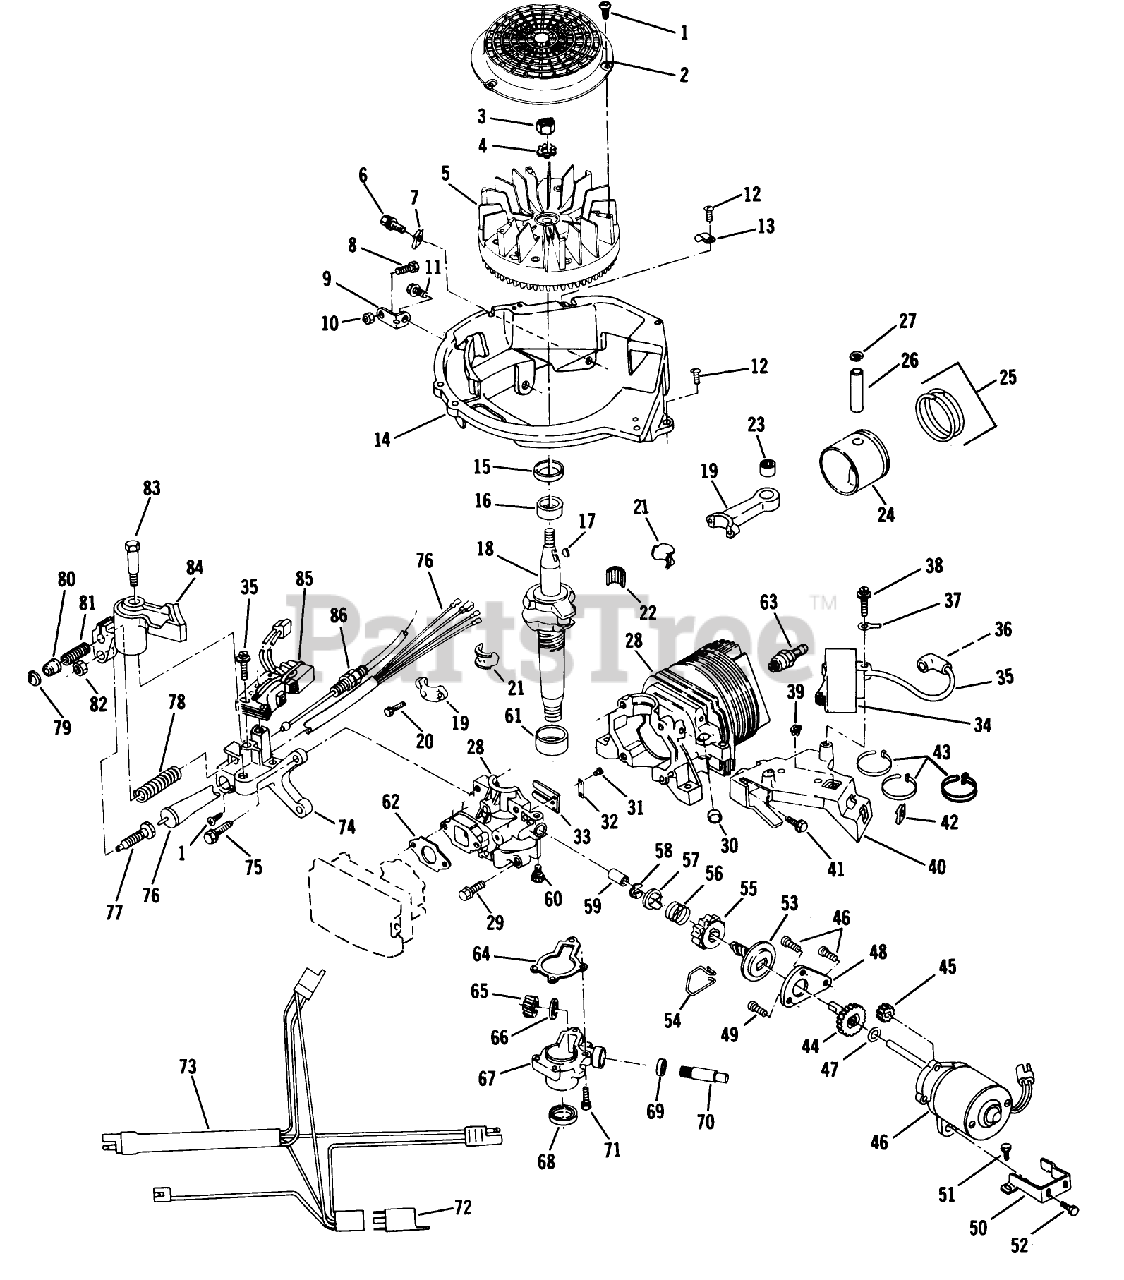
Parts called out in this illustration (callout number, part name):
1	SCREW F
2	SCREEN F'WHEEL S
3	NUT
6	SCREW-SEMS
8	BOLT F
10	NUT-LOCK F
12	SCREW F
14	BASE SHROUD F
16	BEARING V
17	KEY
20	SCREW-HSH
21	LINER ASM
23	BEARING AY F
27	RING-RETAINING
29	SCREW S
30	PLUG-CORE VF
32	PLATE-BACKUP, REED
35	HT LEAD&COVER XEV
37	TERMINAL S
39	NUT-CLIP
42	NUT - SPEED S
44	GEAR-DRIVEN
45	*PINION EF
49	SCREW EF
50	BRACKET
52	SCREW
54	SPRING F
55	PINION EF
56	*SPRING PINION EF
58	RET.RING EF
59	SLEEVE F
61	BEARING S
62	GASKET CARB S
64	GASKET S
65	GEAR, DR SHAFT S
66	THRUST WASHER
68	SEAL-OIL
69	SEAL S
74	BRACKET F
77	PLUNGER S
78	SPRING-BRAKE
79	RETAINER S
80	ACTUATOR-LEVER, BRAKE
81	SPRING
86	CONTROL CABLE
